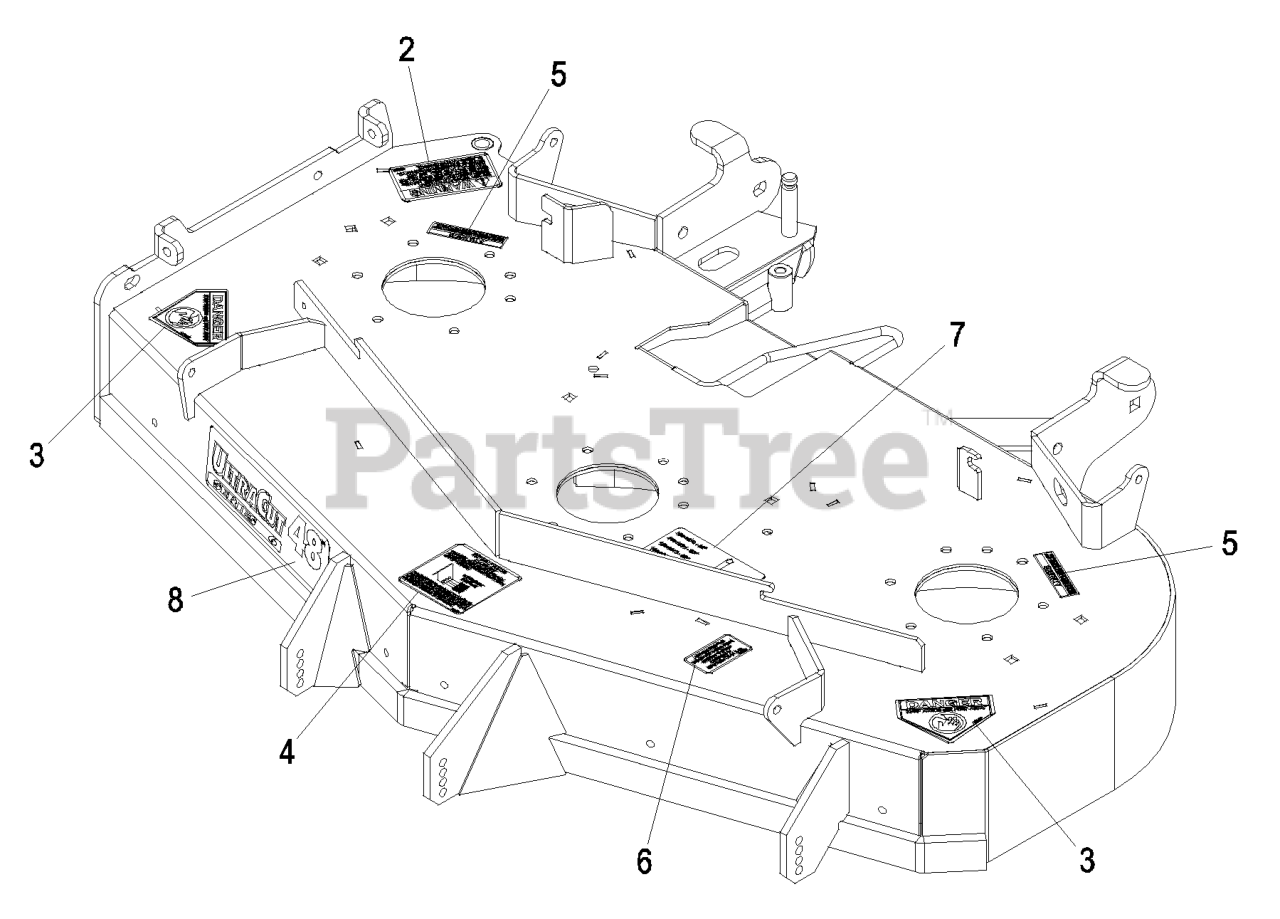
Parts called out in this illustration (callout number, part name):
2	DECAL-WARNING, DISCHARGE
3	DECAL-DANGER
4	DECAL,ANTISCALP
5	DECAL-COVER, MISSING
6	DECAL,BOLT TORQUE
7	DECAL,BELT ROUTING
8	DECAL,ULTRACUT 48 SERIES
